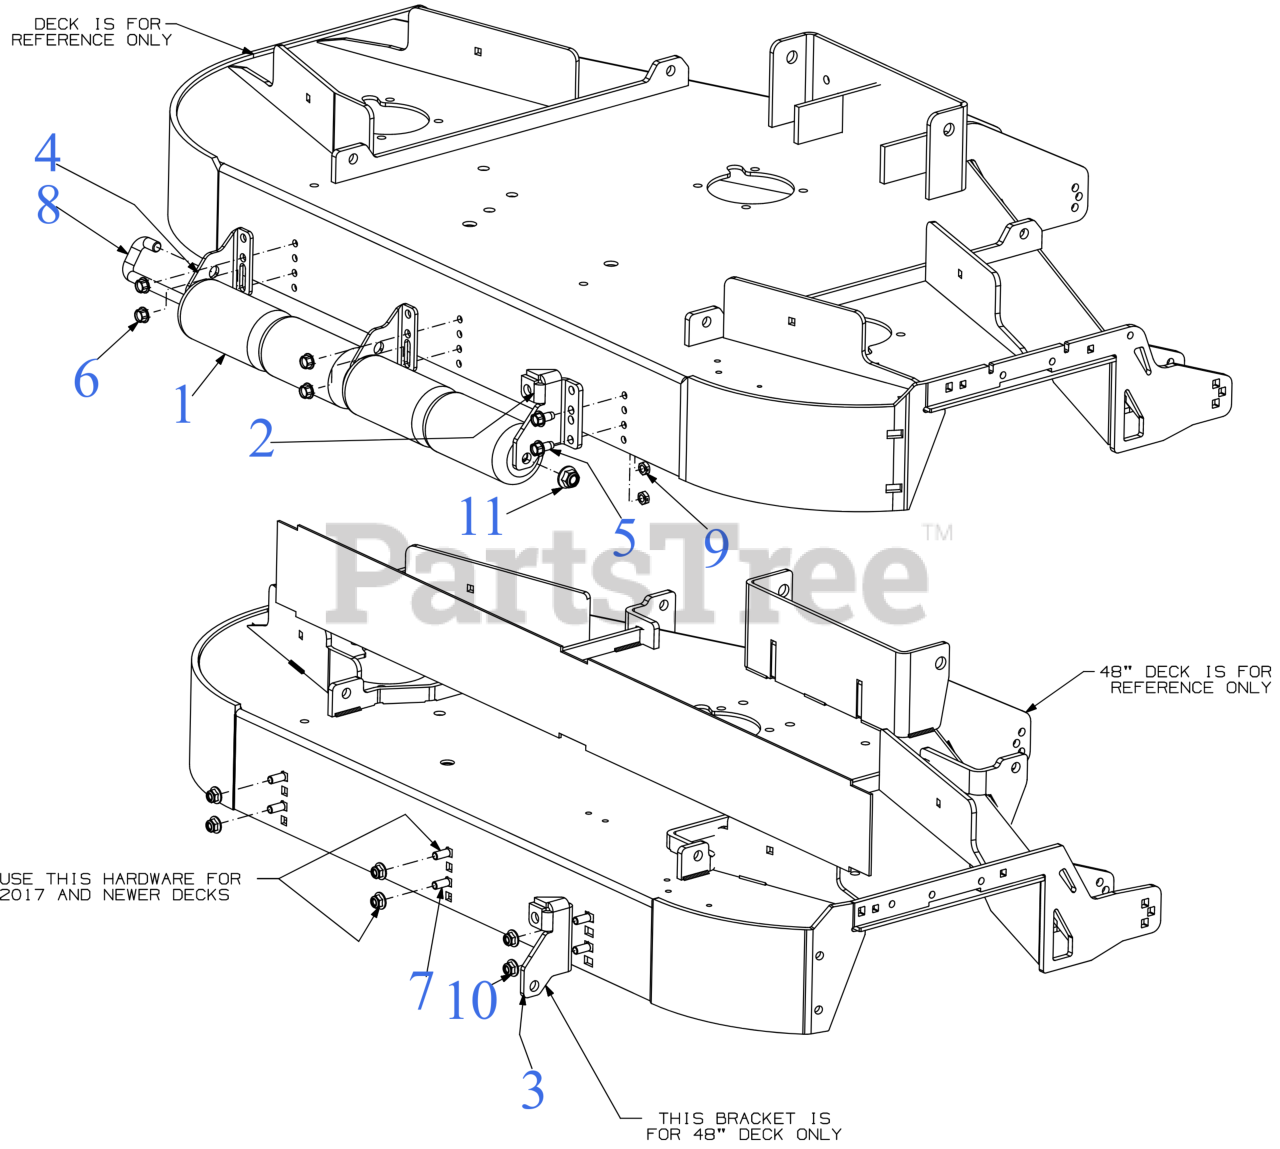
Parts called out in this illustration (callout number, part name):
1	ROLLER ASSEMBLY
2	REAR ROLLER DECK BRACKET
3	REAR STABILIZER BRACKET
4	REAR MOUNT BRACKET
5	SCREW 3/8-16 x 3/4
6	SCREW 3/8-16 x .500
7	CARRIAGE BOLT 3/8-16 x 1.00 GR5
8	ROLLER PIN
9	JAM LOCK NUT
